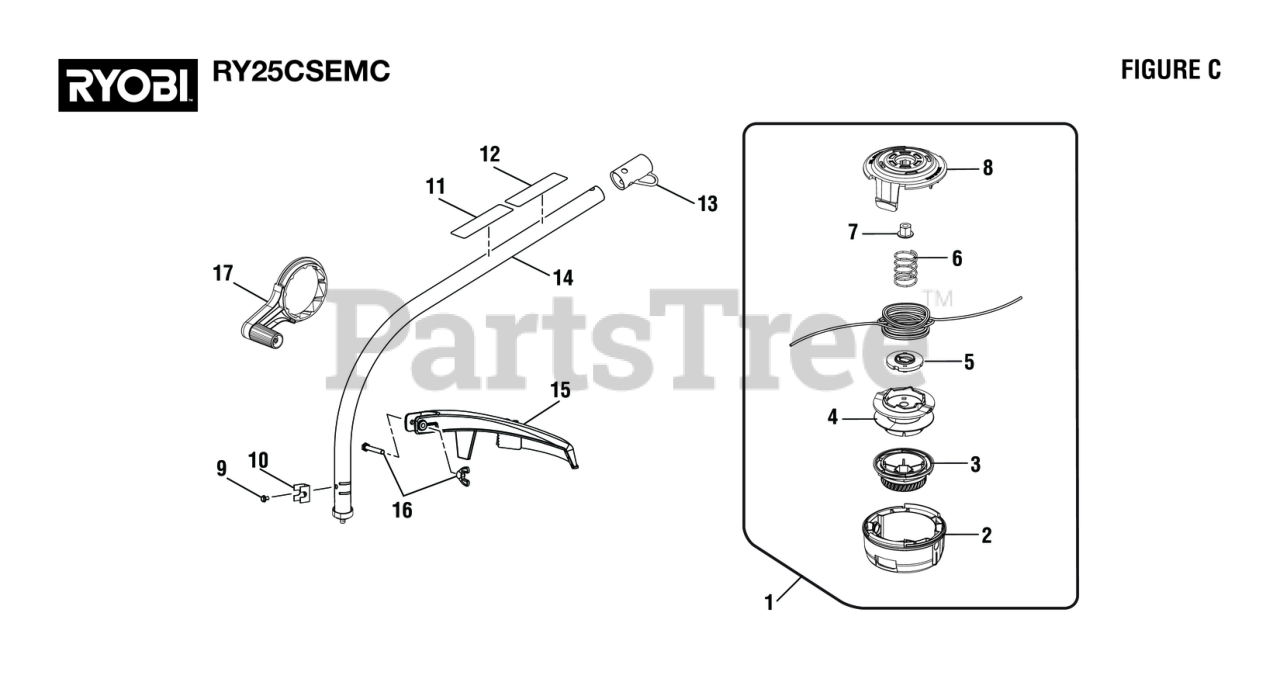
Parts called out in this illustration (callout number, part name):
1	Trimmer Head Assembly (.095)
2	Lower Housing
3	Bump Knob (Green)
4	Spool Assembly
5	String Guide
6	Compression Spring
7	Flange Nut (M8)
8	Upper Housing
9	Screw (#10-32 x 3/8 in., Hex Washer Hd. S.T.)
11	Ryobi EXPAND-IT Label
12	Warning Icon Label
13	Storage Hanger Cap
14	Curved Shaft Assembly
15	Grass Deflector Assembly
16	Fastener Parts Kit
17	Crank Handle
